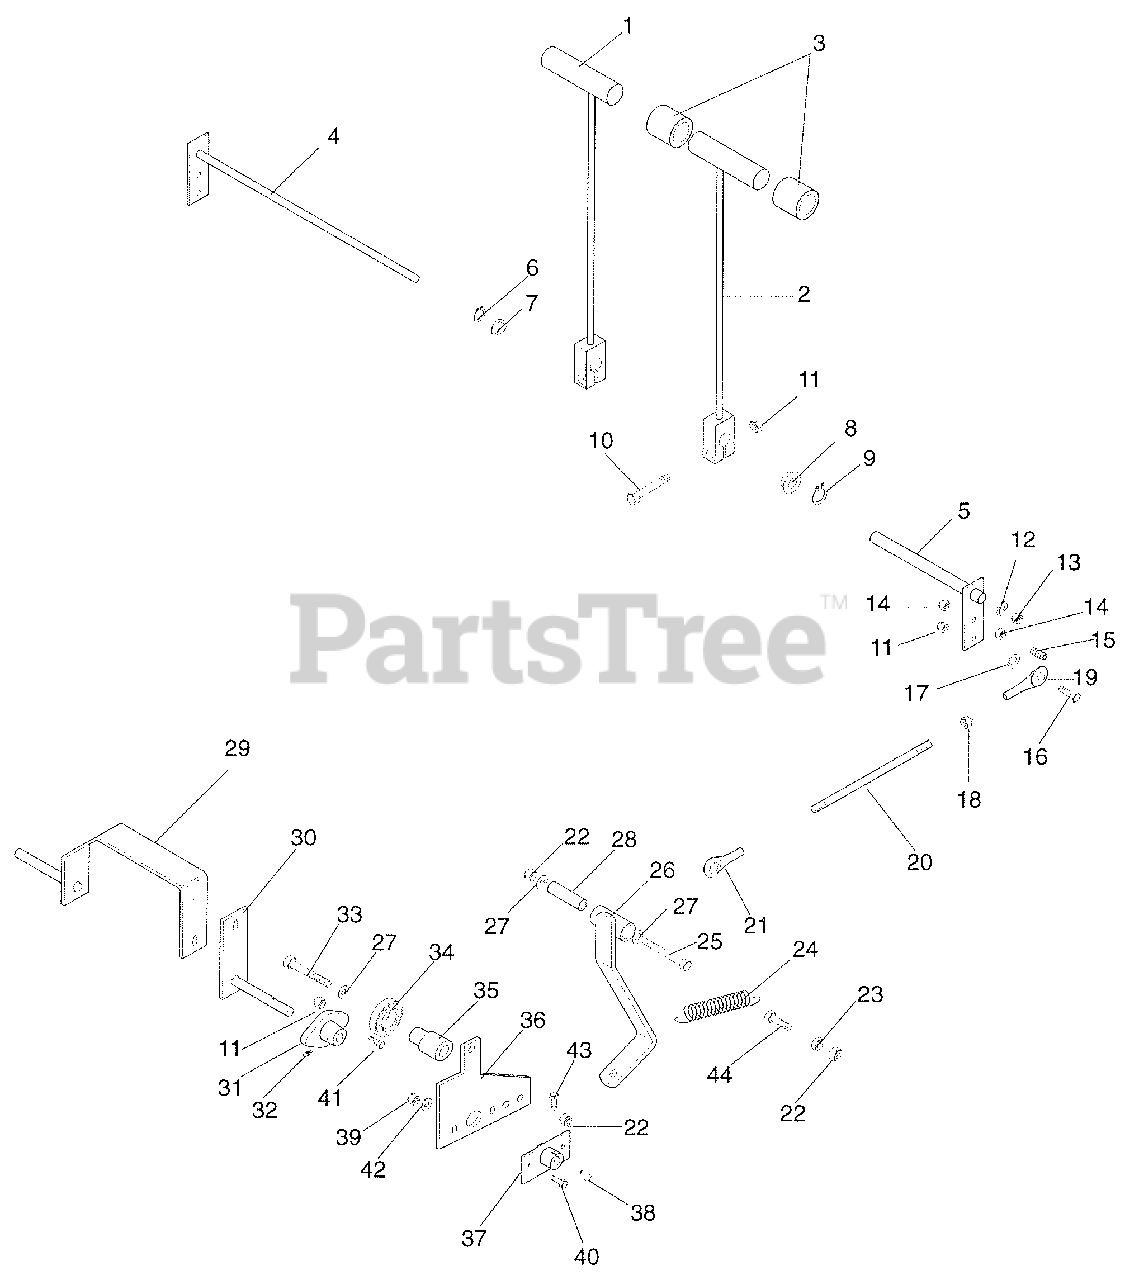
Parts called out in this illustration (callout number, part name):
1	Weldment, Steering Lever LH
2	Weldment, Steering RH
3	Grip, T-Bar
4	Weldment, Steering Rod
5	Weldment, Steering Tube
6	Ring Retaining External .500 X .460
7	Bushing Flange .515 X .750 X .745 X 1.00
8	Bushing Flange .762 X 1.0 X .580 X 1.48
9	Ring Retaining External .689 X .077
10	Bolt Hex .31-18 X 1.50 Grade 5
11	Nut Locking Nylon .312-18 Grade 2
12	Washer Flat Steel .531 X 1.062 X .095
13	Nut Locking Nylon .50-13 Grade 2
14	Nut Hex .312-18 Grade 2
15	Screw Set .32-18 Grade 2
16	Bolt Hex .31-18 X 1.25 Grade 2
17	Washer Flat Steel .344 X .688 X .065
18	Nut - 5/16-24, Hex, Plated
19	Rod End, 5/16" Female
20	Rod, Steering Adjusting
21	Rod End, 5/16-24 Left Hand Female
22	Nut Locking Nylon .375-16 Grade 2
23	Nut Hex .375-16 Grade 2
24	Spring-Tens .063 X .62 X 2.75
25	Bolt Hex .38-16 X 2.75 Grade 5
26	Weldment, Neutral Detent
27	Washer Flat Steel .406 X .812 X .065
28	Bushing, Steel .385 X .610 X 1.80
29	Weldment, Pump Control RH
30	Weldment, Pump Control LH
31	Bushing, Flanged Support
32	Fitting-Lube .25-28 X .256
33	Bolt Hex .38-16 X 2.00 Grade 5
34	Bearing Ball .500 X 1.375 X .437
35	Hub, Bearing Mount
36	Arm, Speed Control
37	Weldment, Neutral Adjuster
38	Key, Woodruff .13 X .75
39	Nut Locking Nylon .250-20 Grade 2
40	Bolt Hex .25-20 X .75 Grade 5
41	Bolt Hex .31-18 X 1.00 Grade 5
42	Washer Flat Steel .281 X .620 X .065
43	Bolt Hex .25-20 X .50 Grade 5
44	Bolt Hex .38-16 X 1.125
